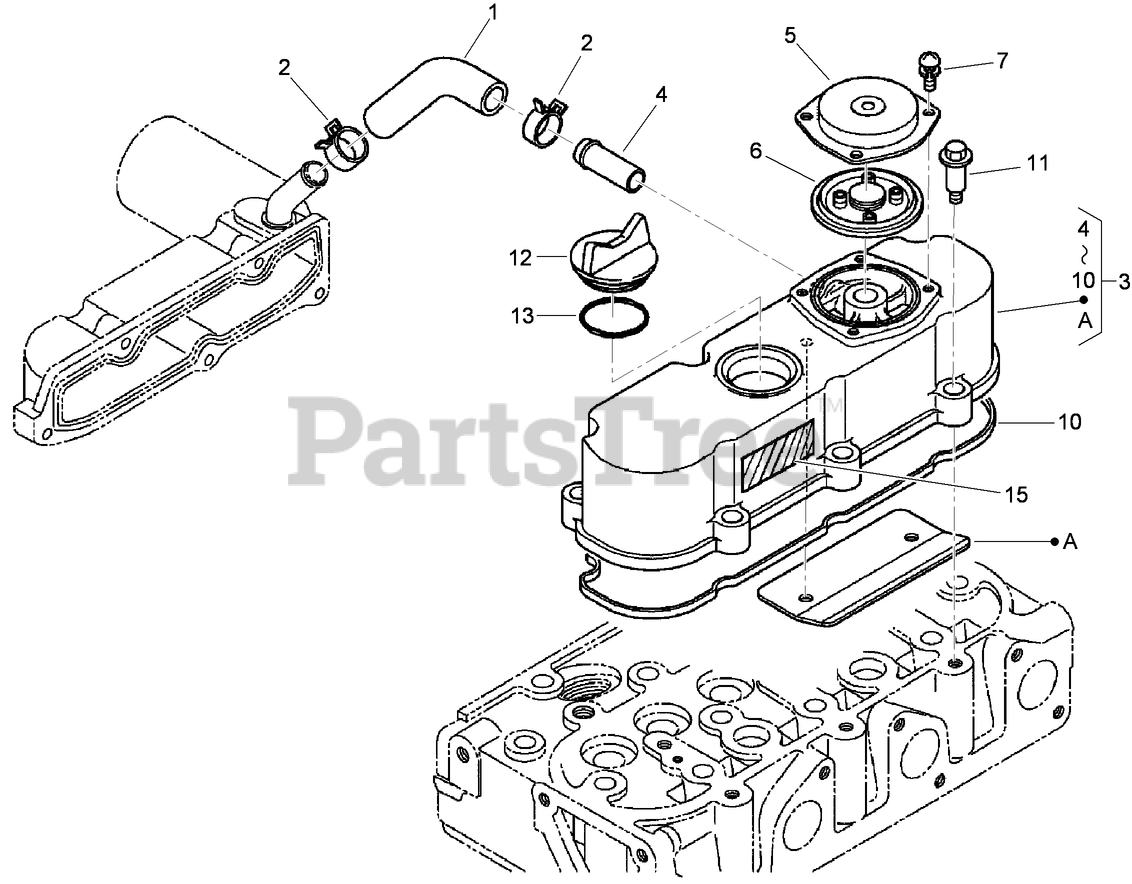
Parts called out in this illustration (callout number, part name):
1	TUBE-BREATHER
2	CLAMP-HOSE
3	CYLINDER HEAD COVER ASM
4	PIPE-RETURN, WATER
5	COVER-BREATHER
6	VALVE-BREATHER
7	SCREW (WITH WASHER)
10	GASKET-COVER, HEAD
12	PLUG-FILLER, OIL
13	O-RING
15	LABEL-INSTRUCTION
